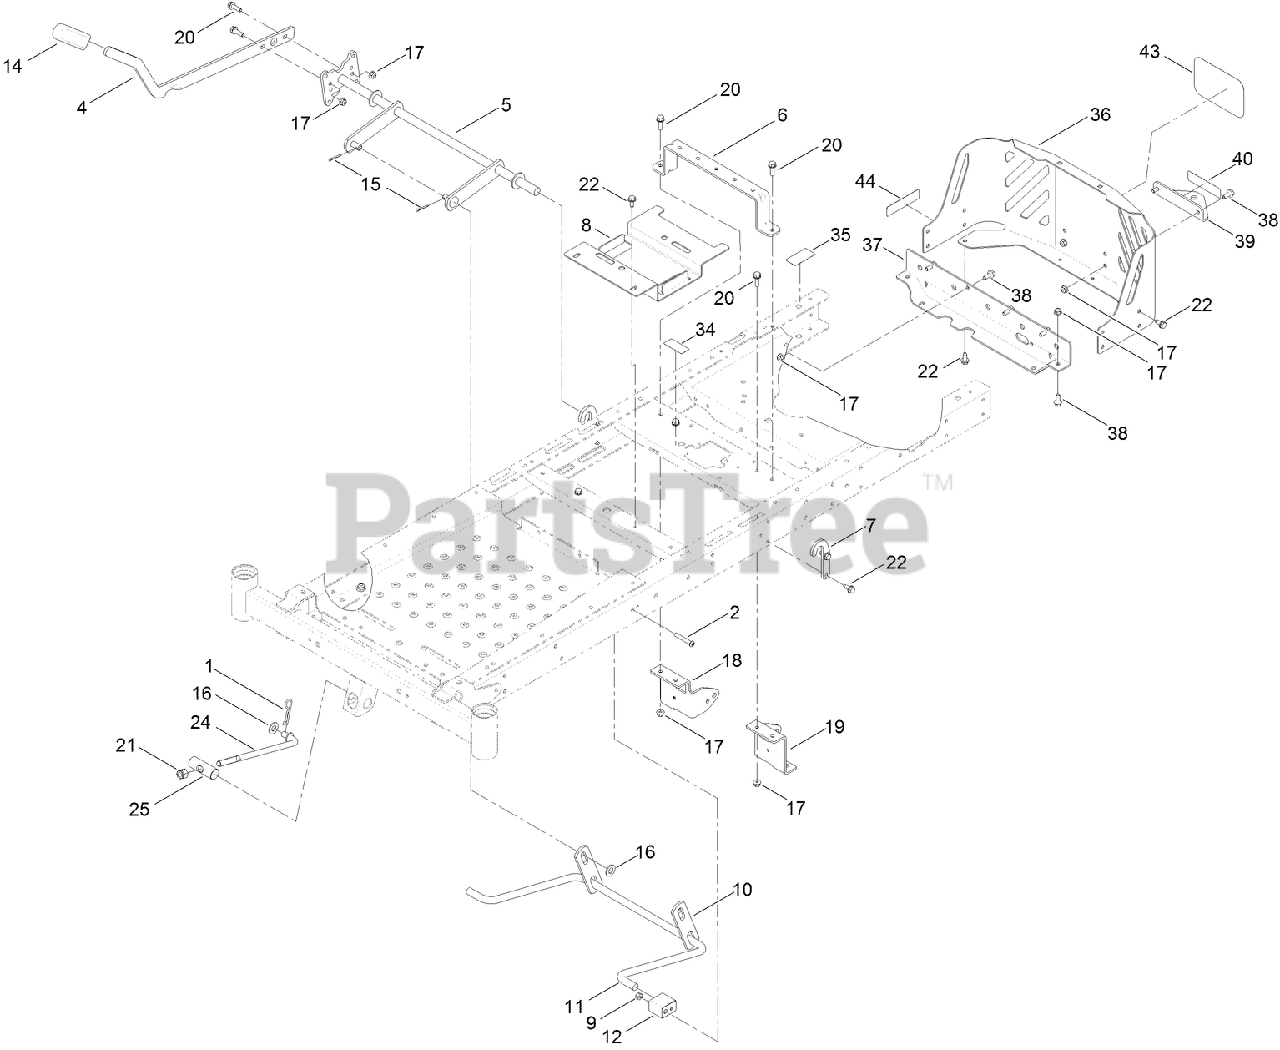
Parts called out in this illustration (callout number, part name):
1	PIN-COTTER
2	SCREW-HSBH
4	LEVER-LIFT
5	LIFT-DECK, NARROW
6	BRACE-SEAT, REAR (NARROW)
7	BRACKET-LIFT
8	BRACKET-BATTERY
9	NUT-LOCK, NI
10	LINK-LIFT
11	ARM-LIFT, REAR
12	BLOCK-PIVOT
14	GRIP-LEVER
15	PIN-COTTER
16	WASHER-FLAT
17	NUT-HF, NI
18	MOUNT-HYDRO, FRONT (RH)
19	MOUNT-HYDRO, FRONT (LH)
20	SCREW-HHF
21	NUT-HEX
22	SCREW-HWHTF
24	ROD-MOUNT, DECK
25	PIN-PIVOT
34	DECAL-LOCATION, SERVICE DEALER
35	DECAL-BYPASS
36	GUARD-ENGINE, NARROW
37	CROSSMEMBER-REAR, NARROW
38	SCREW-HHF
39	BRACKET-HITCH
43	DECAL
44	DECAL-ARRESTER, SPARK
